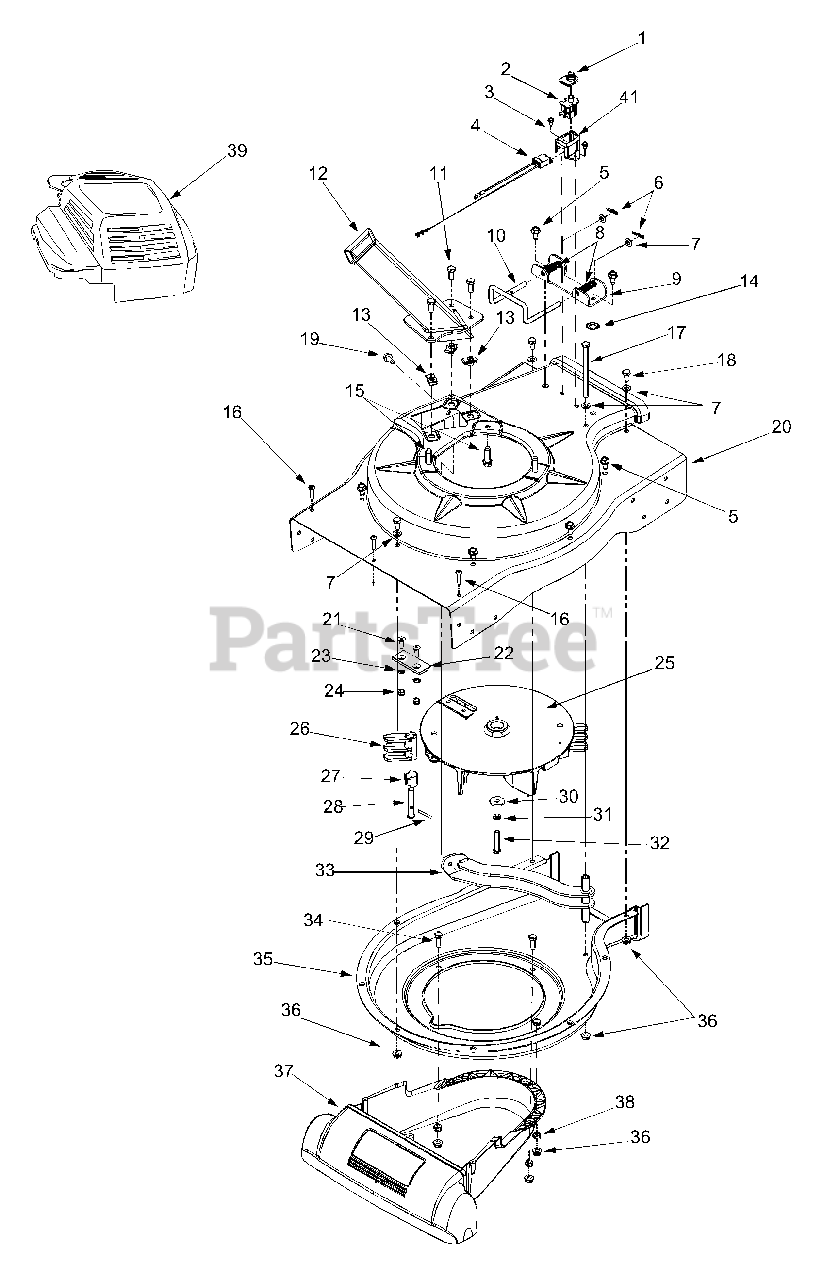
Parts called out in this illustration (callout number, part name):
1	Switch Cover
2	Safety Switch
3	Hex Washer Screw #10-16 x .50
4	Wire Harness
5	Hex Washer Screw 5/16-18 x .625
6	Cotter Pin
7	Flat Washer.330 ID x.630 OD
8	Compression Spring
9	Mounting Bracket
10	Lock Rod
11	Hex Cap Screw 5/16-18 x .75
13	U-Clip Lock Nut 5/16-18
14	External Lock Washer 5/16
15	Hex Washer Screw 3/8-16 x 1.25
16	Screw #12-16 x 1.0
17	Hex Cap Screw 5/16-18 x 4.5
18	Hex Cap Screw 5/16-18 x .625
19	Hex Washer Screw 5/16-18 x .625
22	Chipper Blade
23	Lock Washer 5/16
24	Hex Lock Nut 5/16-24
25	Impeller Assembly
26	Flail Blade
27	Pin Clip
28	Clevis Pin
29	Spiral Pin
30	Flat Washer.375 ID x 1.25 OD
31	Lock Washer 3/8
32	Hex Cap Screw 3/8-24 x 2.0
33	Screen Assembly
34	Hex Cap Screw 5/16-18 x .875
36	Lock Nut 5/16-18
37	Nozzle Cover
38	Lock Nut 5/16-18
41	Safety Switch Cover
